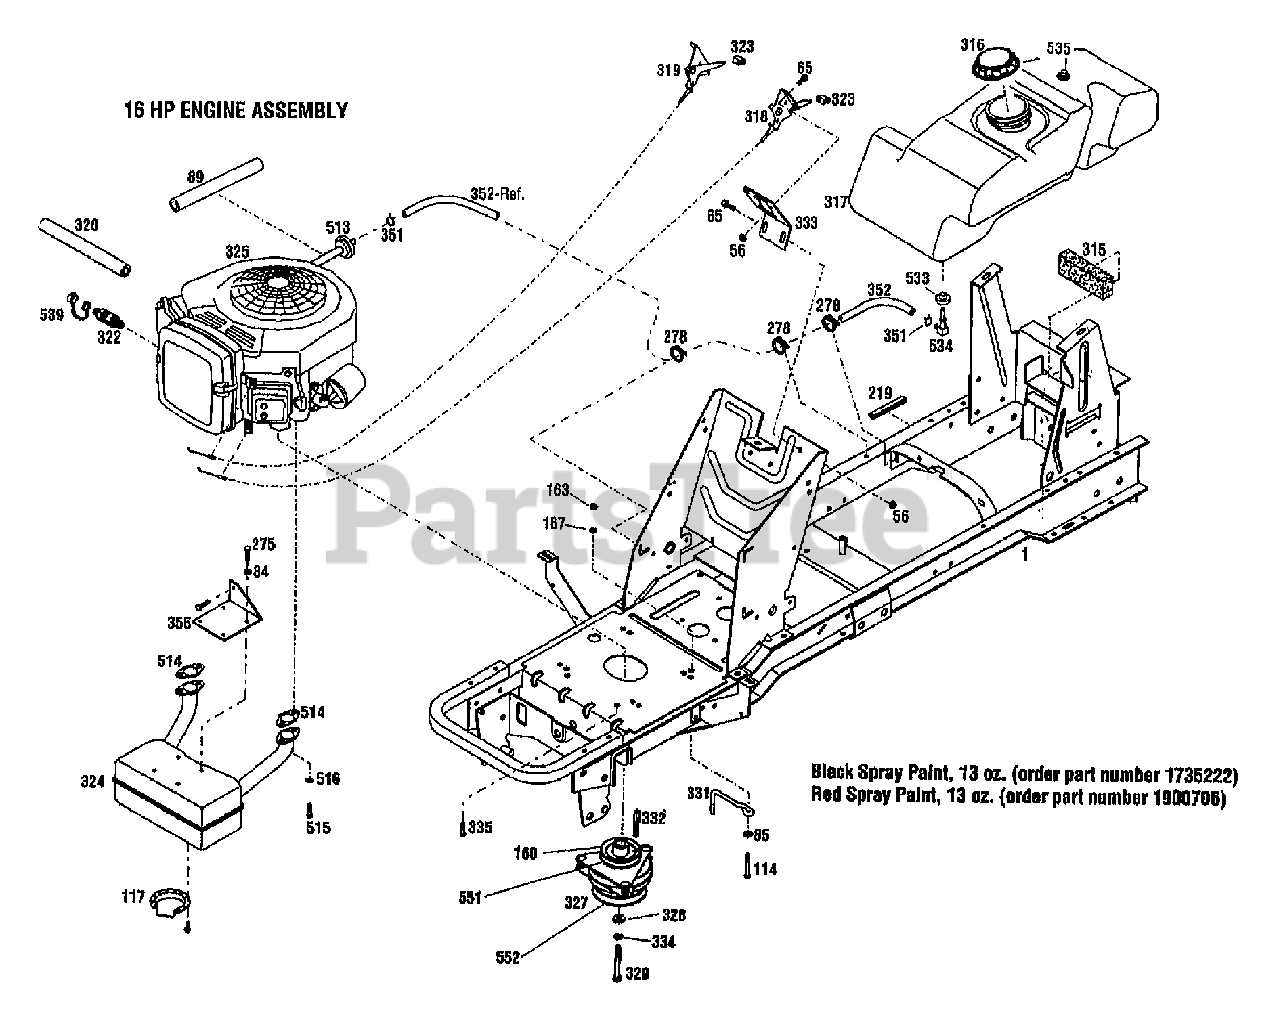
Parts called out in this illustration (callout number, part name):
1	ASSM-FRAME LTX
56	NUT-HF/LK 1/4-20 ZP
65	SCR-HH 1/4-20X.625
84	WASHER-LK .25 ZP
85	WASHER-FLAT 3/8 SAE
89	INSULATION-FUEL LINE
114	SCR-THRD FRM 3/8-16X1.50
117	DEFLECTOR-MUFFLER
160	PULLEY-ENGINE
163	NUT-HEX 3/8-16 ZP
275	SCR-HH 1/4-20X.625 G5 ZP
278	TIE-CABLE NYLON BLACK
315	PAD-FUEL TANK
316	CAP-FUEL
317	TANK-FUEL
318	CONTROL-CHOKE
319	THROTTLE-CONTROL
320	HOSE-OIL DRAIN
322	ASSM-OIL VALVE
325	ENGINE, 16HP, MODEL 303777
327	CLUTCH-ELECTRIC
328	WASHER-SPEC 1.42X.468X.25 ZP
329	SCR-HH 7/16-20X3.00
331	CLUTCH-RETAINER
332	KEY-.25 SQ X 2.5
333	BRKT-MOUNTING CONTROL
334	WASHER-LK .438 ZP
335	SCR-HH 3/8-16X1.0 THDFM
351	CLAMP-HOSE
352	LINE-FUEL
355	BRKT-MUFFLER
513	FILTER-FUEL
514	MUFFLER GASKET
515	SCR-HH 1/4-20X1.0
516	WASHER-LK .25 ZP
533	BUSHING-RUBBER
534	ELBOW-90 DEG (FUEL LINE)
535	VENT-FUEL TANK
539	CAP-OIL DRAIN
551	BEARING-UPPER CLUTCH
552	BEARING-CLUTCH LOWER
